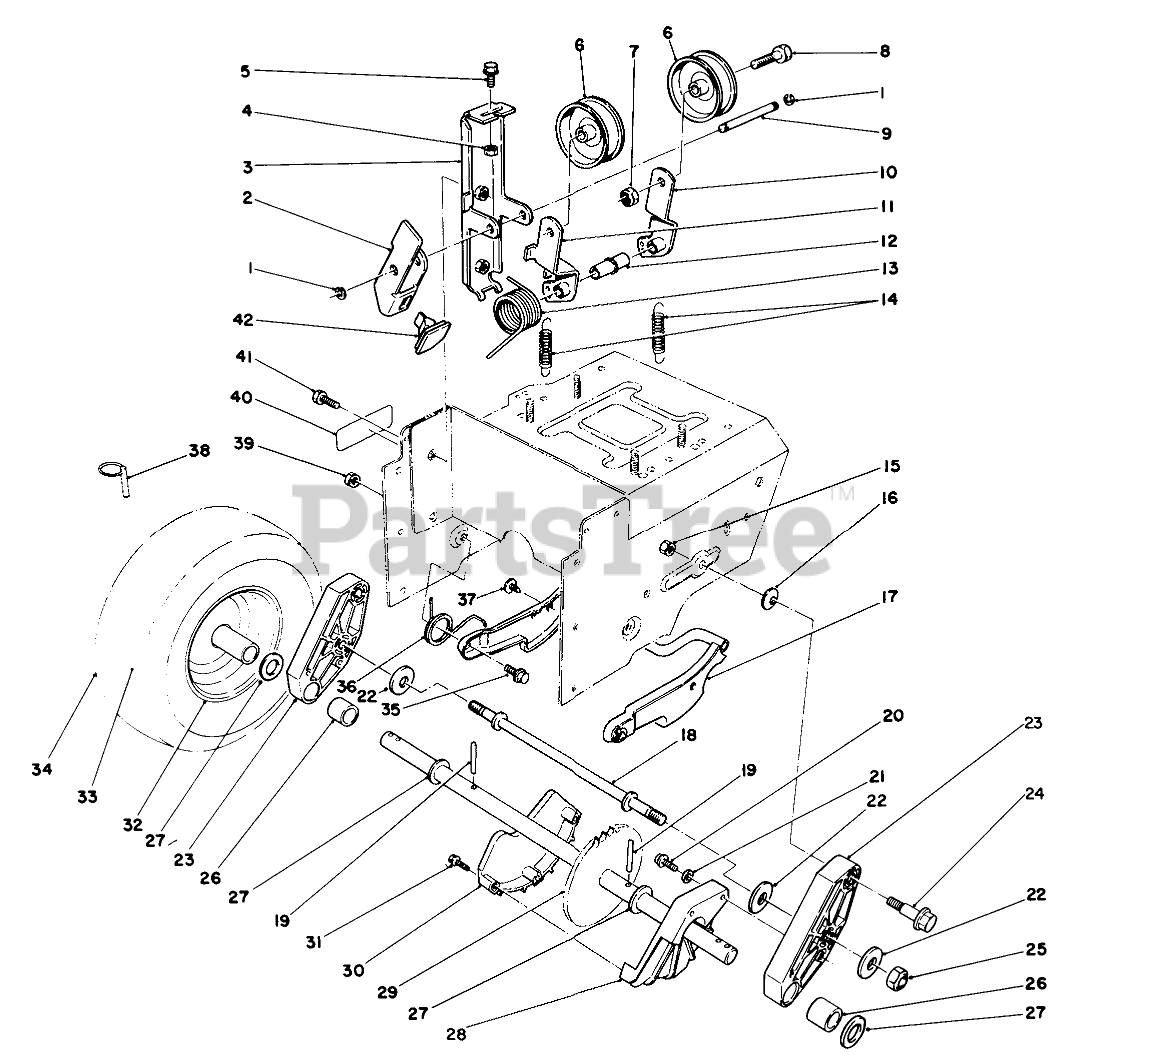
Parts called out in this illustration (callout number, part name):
1	RING-RETAINING
2	ARM-BRAKE
3	IDLER ARM BRACKET ASM
4	NUT-LOCK, NI
5	SCREW-HHF
6	PULLEY-IDLER
7	NUT-LOCK, NI
8	SCREW-HH
9	PIN-IDLER
10	ARM-IDLER, TRACTION
11	ARM-IDLER, IMPELLER
12	BUSHING-IDLER
13	TORSION SPRING
14	SPRING-EXTENSION
15	NUT-LOCK, NI
16	WASHER-SPRING
17	Latch-Arm
18	ROD-LATCH
19	PIN-ROLL, SLOTTED
20	SCREW-HWH
21	WASHER-FLAT
22	WASHER-SUPPORT
23	Pivot Arm Assembly (Incl. Ref. #26)
24	BOLT-SHOULDER
25	NUT-LOCK, NI
26	BUSHING-AXLE
27	WASHER-THRUST
28	GUARD-CHAIN, LH
30	GUARD-CHAIN, RH
31	SCREW-PPH
32	RIM-WHEEL
33	INNER TUBE
35	SCREW-SHOULDER
36	SPRING-LATCH, TORSION
37	FASTENER-PANEL
38	PIN-LYNCH
39	NUT-LOCK, NI
40	DECAL-WARNING
41	SCREW-HHF
42	PAD-BRAKE
